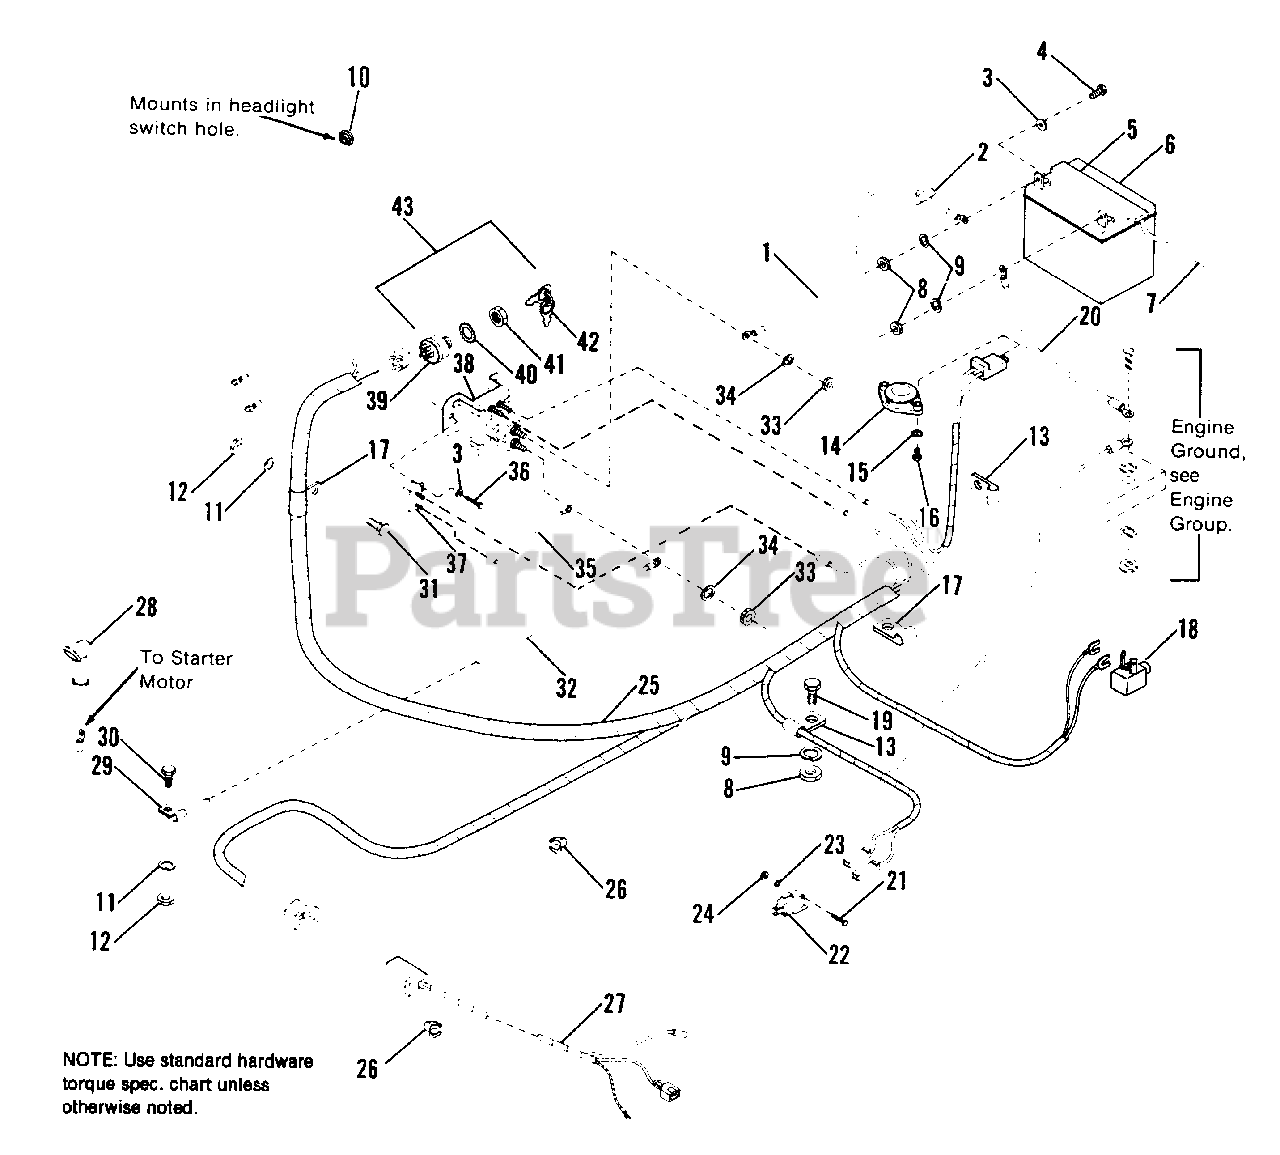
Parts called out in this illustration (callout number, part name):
1	WIRE ASSY., Battery to Solenoid
2	BOOT, Insulator
3	WASHER, Plain
4	CAPSCREW, Hex, 1/4-20 x 3/4
5	VENT CAP, Battery
7	HOSE, Drain, Battery
8	NUT, Hex, 1/4-20
9	LOCKWASHER, Spring, 1/4
10	BUTTON, Plug
11	LOCKWASHER, Spring, 5/16 (Qty. 3 used on 16 HP)
12	NUT, Hex, 5/16-18 (Qty. 3 used on 16 HP)
14	SWITCH ASSY., Safety, Seat
15	LOCKWASHER, External Tooth, 1/4
16	SCREW, Round Head, 1/4-20 x 3/4
18	SWITCH, Interlock, PTO
19	CAPSCREW, Hex, 1/4-20 x 5/8
20	WIRE ASSY., Battery to Engine Ground (16 HP)
20	WIRE ASSY., Battery Engine Ground (18 & 20 HP)
21	CAPSCREW, Hex, #5-40 x 3/4
22	MICROSWITCH, Interlock
23	LOCKWASHER, Spring, #5
24	NUT, Hex, #5-40
25	HARNESS ASSEMBLY, Lever Steer
26	CLIP (16 HP)
27	WIRE ASSY., Harness to Engine (16 HP)
29	CLAMP, Wire (16 HP)
30	CAPSCREW, Hex, 5/16-18 x 3/4 (16 HP)
31	CAPSCREW, Hex, 5/16-18 x 1
32	WIRE ASSY., Solenoid to Starter (16 HP)
32	WIRE ASSY., Solenoid to Starter (18 & 20 HP)
33	NUT, Hex, 5/16-24
34	LOCKWASHER, Spring, 5/16
35	WIRE, Circuit Breaker to Solenoid
36	SCREW, Taptite, 1/4-20 x 5/8
37	CIRCUIT BREAKER
38	SOLENOID
40	LOCKWASHER, Internal Tooth, 5/8
41	NUT, Hex, 5/8-32
42	KEYS & RING
43	IGNITION SWITCH ASSY., (Incl. Ref. Nos. 39-42)
